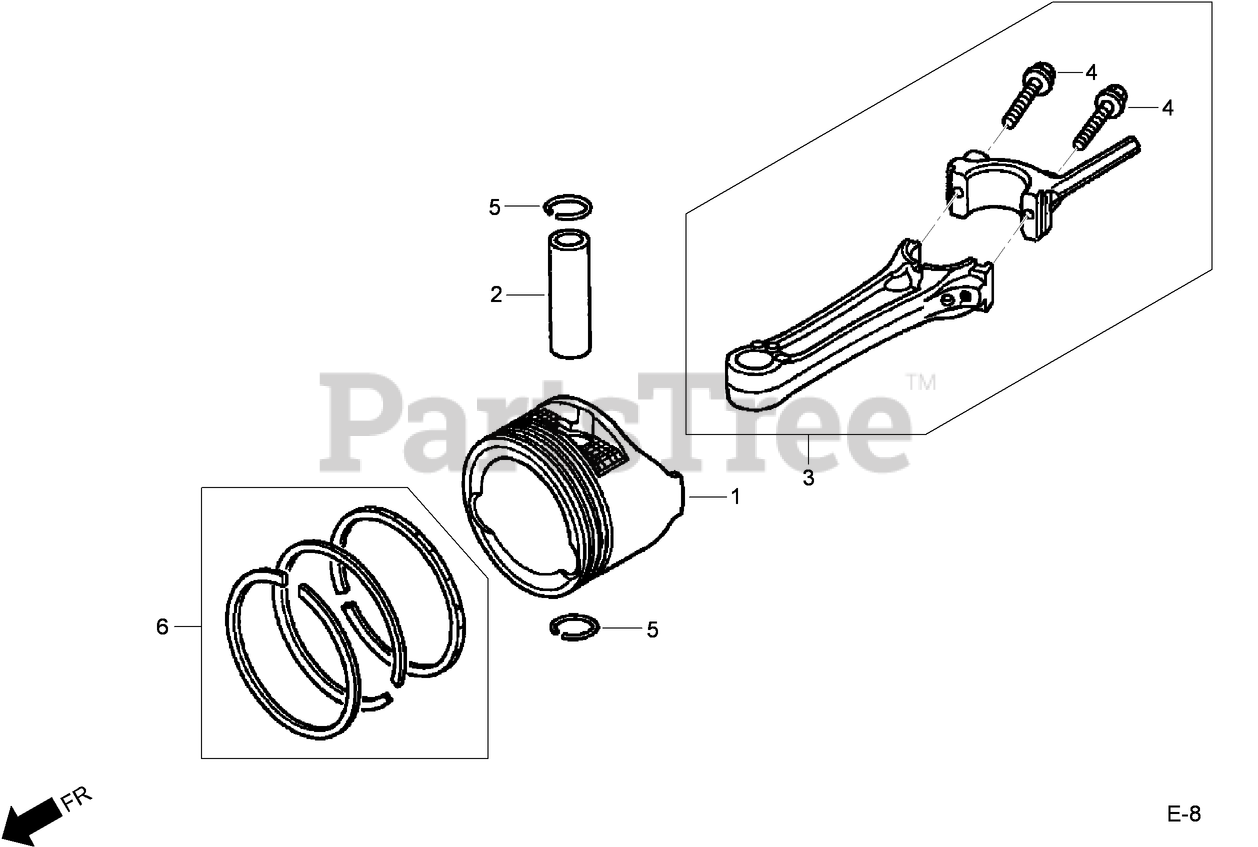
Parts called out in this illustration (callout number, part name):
1	PISTON (engine serial numbers up to 5383514)
1	PISTON
2	PIN-PISTON
3	CONNECTING ROD ASM
4	BOLT-ROD, CONNECTING
5	CLIP-PIN, PISTON (13MM)
6	PISTON RING SET (RIKEN) (engine serial numbers up to 5383514)
6	PISTON RING SET (TEIKOKU) (engine serial numbers up to 5383514)
6	PISTON RING SET (STD) (TEIKOKU) (engine serial numbers up to 5383514)
6	PISTON RING SET (STD) (TEIKOKU) (engine serial numbers starting at 5383515)
